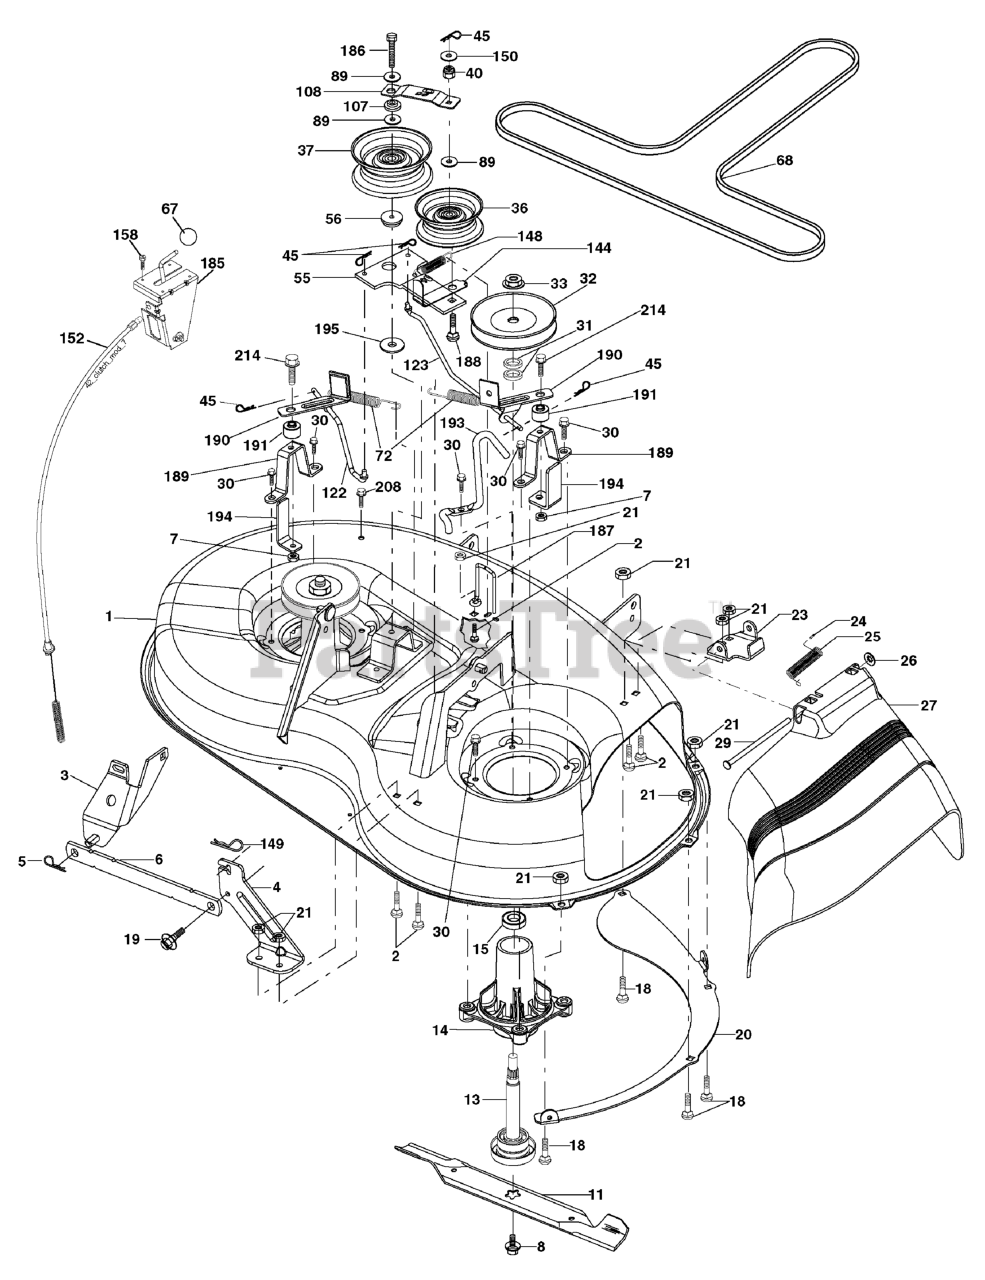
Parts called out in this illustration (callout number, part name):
1	HOUSING, Mower Assembly
2	BOLT, Carriage, 5/16-18 x 3/4
3	BRACKET, Assembly Fr. Sway Bar
4	BRACKET, Deck Sway Bar, 38"/42"
5	RETAINER, Spring
6	BAR, Sway Deck
7	NUT, Lock Hex w/Insert, 5/16-18 UNC
8	BOLT, 3/8-24 x 1.25 Gr 8
11	BLADE, Mower
13	SHAFT, Assembly Mandrel Vented
14	HOUSING, Mandrel Vented
15	BEARING, Ball Mandrel
18	BLADE, Roundhead Squareneck, 5/16-18 x 5/8
19	BOLT, Shoulder
20	BAFFLE, Vortex Front
21	NUT
23	BRACKET, Mower Deflector
24	CAP, Sleeve
25	SPRING, Torsion Deflector
26	NUT, Push
27	SHIELD, Deflector
29	ROD, Hinge
30	SCREW, Threadrolling
31	WASHER, Spacer
32	PULLEY, Mandrel
33	NUT, Toplock
36	PULLEY, Idler Flat
37	PULLEY, Idler Flat
40	NUT, Crownlock 3/8-16 UNC
45	RETAINER
55	IDLER, Arm Assembly
56	SPACER, Retainer
68	V-BELT
72	SPRING, Brake Return
89	WASHER, 13/32 x 13/16 x 11 Ga.
107	SPACER, Retainer
108	STIFFENER, Idler Arm
122	ROD, Brake LH
123	ROD, Brake RH
144	KEEPER, Belt Idler Tension
148	SPRING, Return Idler
149	RETAINER, Spring Yellow
150	WASHER, 9/32 x 3/4 x 10 Ga.
152	CLUTCH, Cable 38"
158	SCREW, Hex Thread Cut, 1/4-20 x 1/2
185	HEAD, Assembly Cable Clutch
186	SCREW, Hex Washer Thread Rolling, 3/8-16 x 2-3/4
187	KEEPER, Belt M Shape
188	BOLT, Carriage Idler
189	BRAKE, Stand
190	BRAKE, Arm
191	BRAKE, Spacer
193	KEEPER, Belt RH Mandrel
194	BRAKE, Guard
195	WASHER, 13/32 x 2 x 10 Ga.
208	SCREW, Thread Rolling, 3/8-16 x 1/2
214	BOLT/WASHER Assembly, 5/16-18
